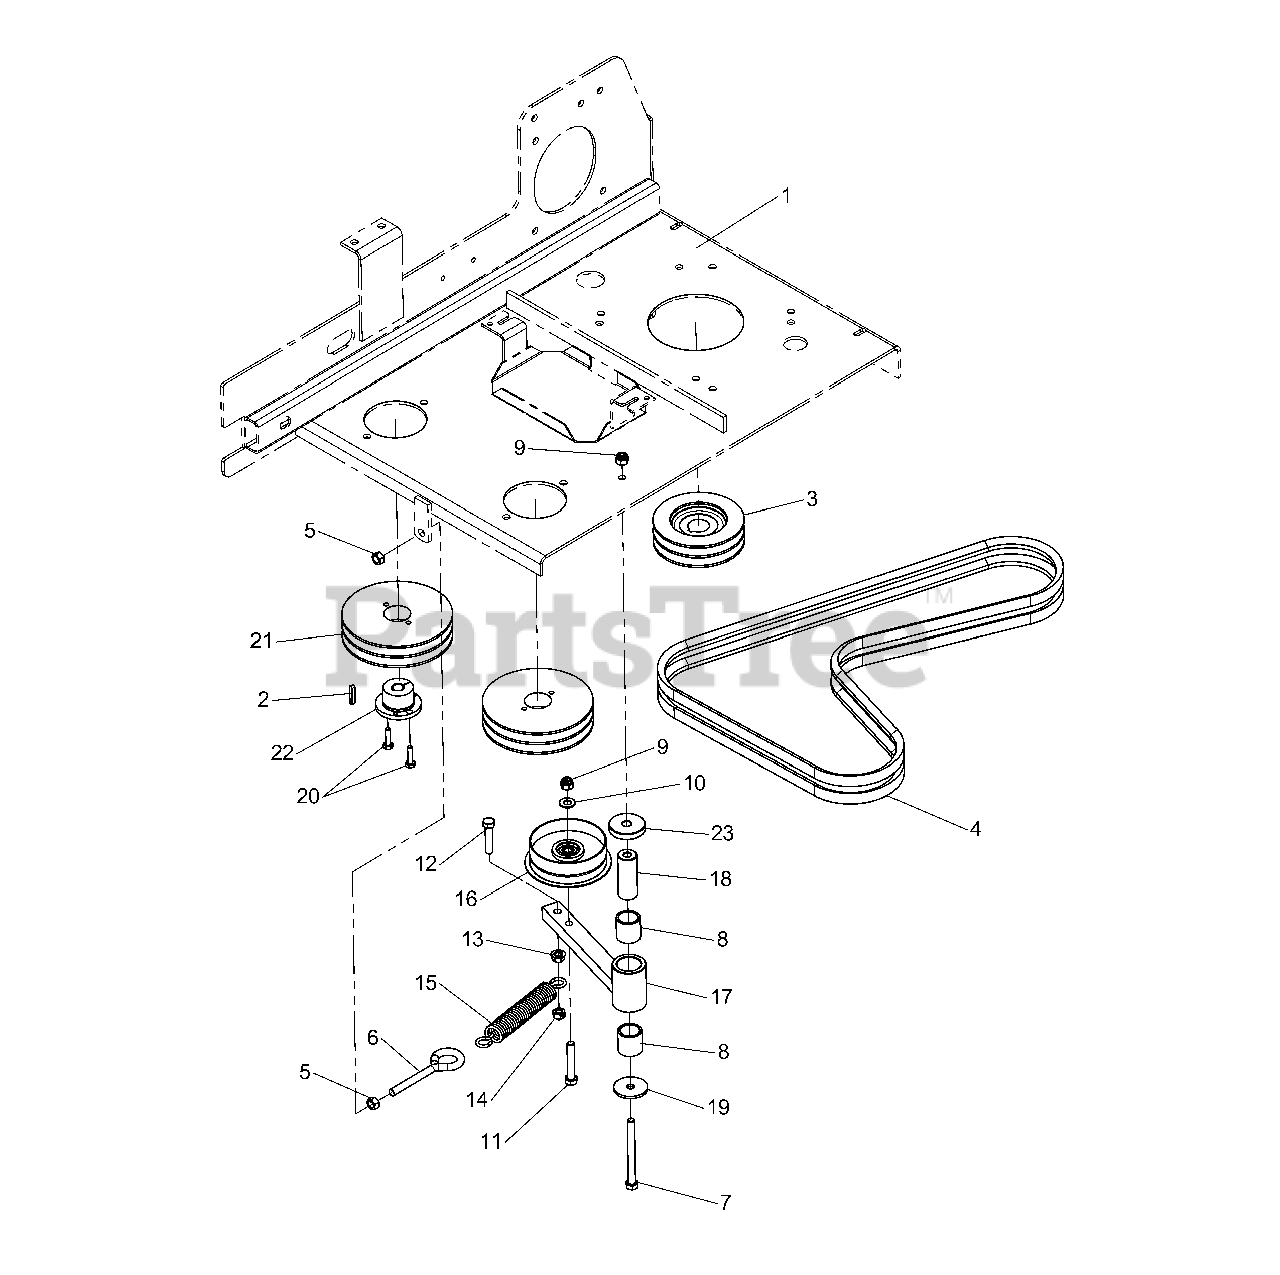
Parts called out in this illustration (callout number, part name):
1	MAIN FRAME (See Main Frame Group)
2	KEY, 5MM SQ. x 25MM w/ Round Ends
3	CRANKSHAFT PULLEY
4	BELT, BANDED A-SEC, 64.76EL, POLY, RAW EDGE
5	NUT, 3/8-16 Hex
6	EYE BOLT, 3/8-16 X 5"
7	BOLT, 3/8-16 X 4"
8	BUSHING, Brass
9	NUT, 3/8-16 Hex Nylon Lock
10	WASHER, 3/8" SAE
11	BOLT, 3/8-16 X 2-1/4"
12	BOLT, 3/8-16 X 1-3/4"
13	NUT, 3/8-16 Hex Large Serrated Flange
14	NUT, 3/8-16 Hex Side Lock
15	SPRING, Extension, Swivel End
16	PULLEY, Idler (Single Flange)
17	See "PUMP DRIVE [Cast Idler Arm for replacing Steel Pump Drive Idler Arm]"
18	SPACER, .39 X 1.00 X 2.55
19	WASHER, 3/8 x 1-3/4
20	BOLT, 1/4-20 X 1", GD
21	PULLEY, Pump Drive
22	BUSHING, Tapered Hub
23	SPACER, .45 X 1.88 X .38
